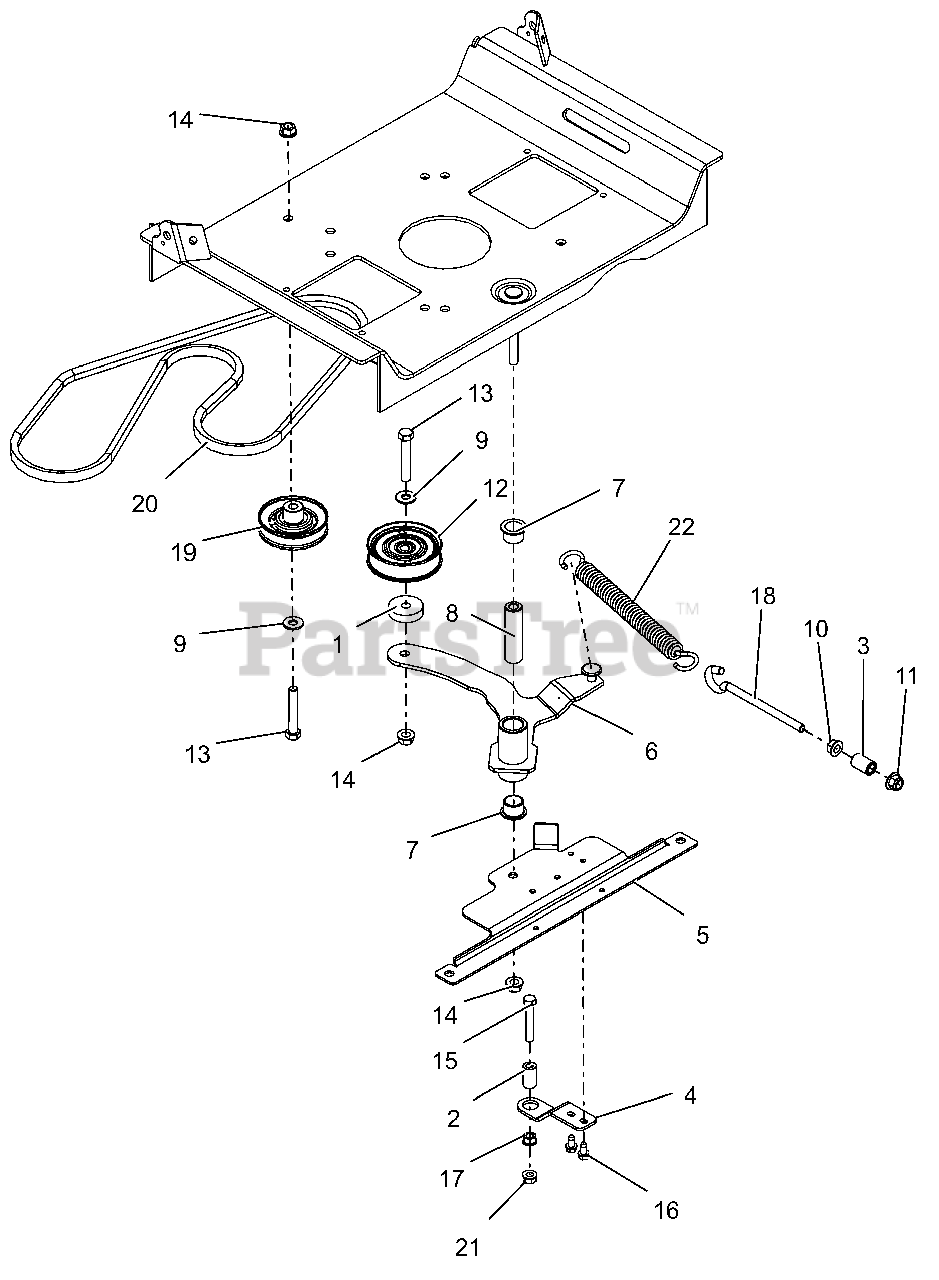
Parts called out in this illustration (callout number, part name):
1	SPACER, .39 X 1.50 X .380
2	SPACER, RUBBER 5/16 IDX1.0 LG
3	SPACER, .375X.625X.970 (PM)
4	BRKT, CLUTCH STOP
5	BRKT, IDLER ATTACHMENT
6	WLDMT,GRD DRIVE IDLER ARM-LGR
7	BSHG-FLG 0.75X0.875X.625X1.125
8	BUSHING, SLEEVE .38X.750X2.78
9	WSHR,FLT .375X.875X.083 ZCC
10	NUT, SPNLK-FLG .38-16 G5 ZCC
11	NUT,NYL-FLG .38-16 GF ZCC
12	IDLER, FLAT - 3.05" X .75"
13	BLT,HEX .38-16X2.25 G5 ZCC
14	NUT-LK-TOP-FLG .38-16 ZC120
15	BLT, HEX .31-18X2.00 G5 ZCC
16	SCR-TAP .25-20X.50 HWH ZCC
17	NUT,SPNLK-FLG .31-18 G5 ZCC
18	BOLT,.38-16 X 4.25-.62 DIA EYE
19	IDLER, V-3.000 OD
20	V-BELT, A-RAW EDGE
21	NUT-LK-TOP-FLG .312-18 GF ZCC
22	SPRING, EXTENSION
